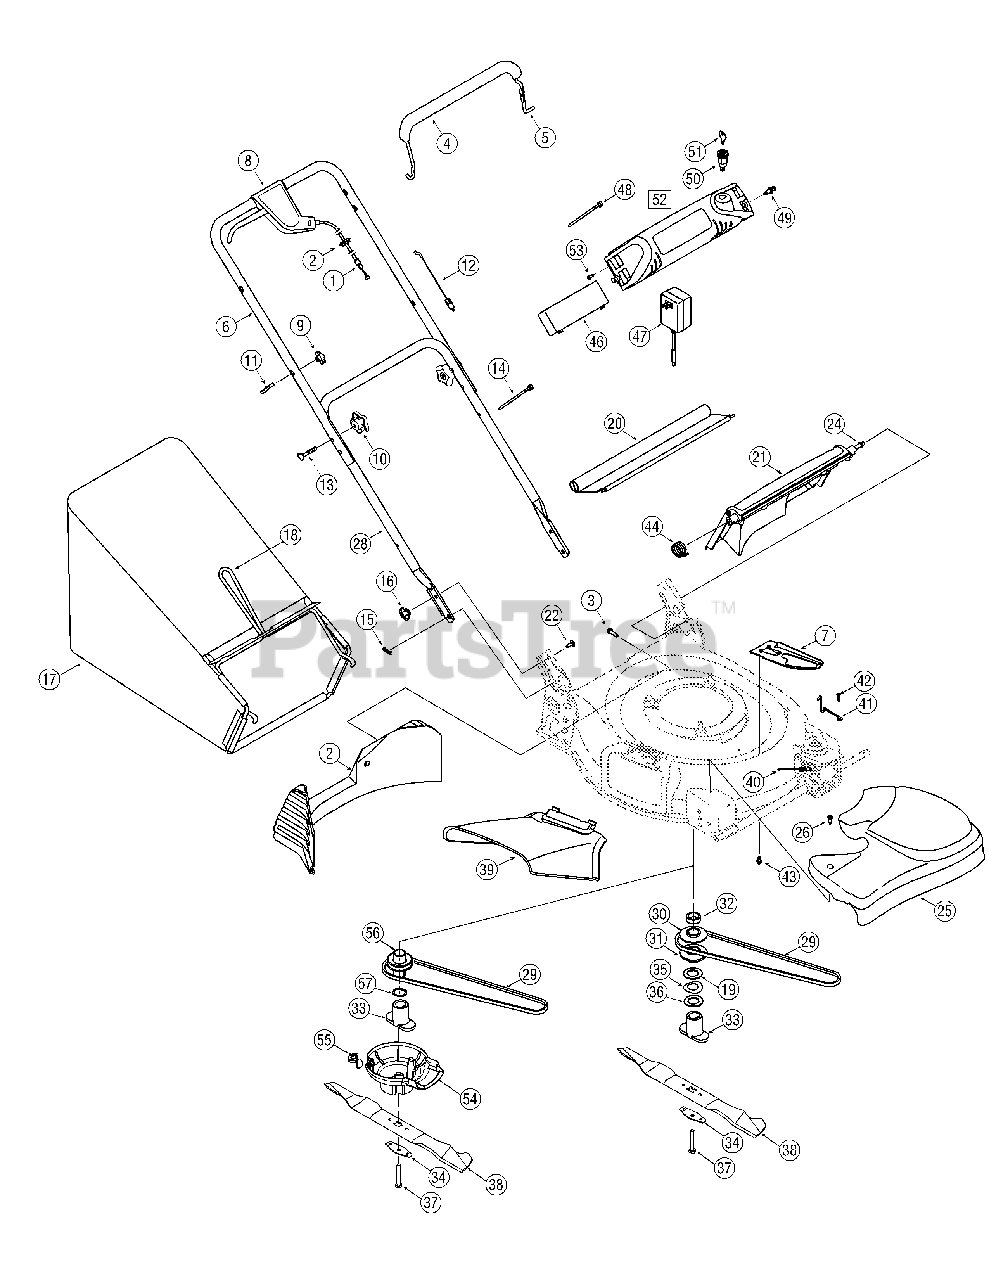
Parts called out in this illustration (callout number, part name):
1	Drive Cable
2	Rear Baffle 21" Rear Discharge
3	Hex Lock Screw 1/4-15 x 1.0
4	Bail Cover - Black
5	Blade Control Handle
6	Upper Handle
7	Cable Mounting Bracket
8	Control Lever Ass'y
10	Knob - Star 5/16-18
11	Rope Guide Bolt
12	Control Cable 37.25" Lg.
13	Carriage Bolt 5/16-18 x 2.0
14	Cable Tie
15	Int. Cot ter Pin .072 x 1.13" Lg.
16	Wing Nut
17	Grass Bag -Generic
18	Grass Bag Frame
21	Rear Discharge Door
22	Carriage Bolt 1/4-10 x .75
25	Transmission Cover (Grey)
26	Shoulder Screw #12-24
30	Upper Pulley Half 25mm x 2.62
31	Lower Pulley Half 25mm x 2.62
32	Sleeve Spacer 25 mm ID x 1.375 x .375
33	Blade Adapter
34	Blade Bell Support
35	Space Washer
37	Hex Bolt 3/8-24 x 2.5" Lg.
38	21" Mulch ing Blade
39	Chute Deflector
40	Extension Spring
41	Belt Keeper Wire
42	Torx Screw
43	Screw 1/4-14 x 0.625
44	Torsion Spring RH
46	12V Battery
47	Battery Charger
48	Cable Tie
52	Electric Starter Har ness Ass'y
53	Screw, #10-16 x .750
54	Engine Baffle
56	Drive Pulley Ass'y
57	Wave Washer 1.35 x 1.05 x 0.015
